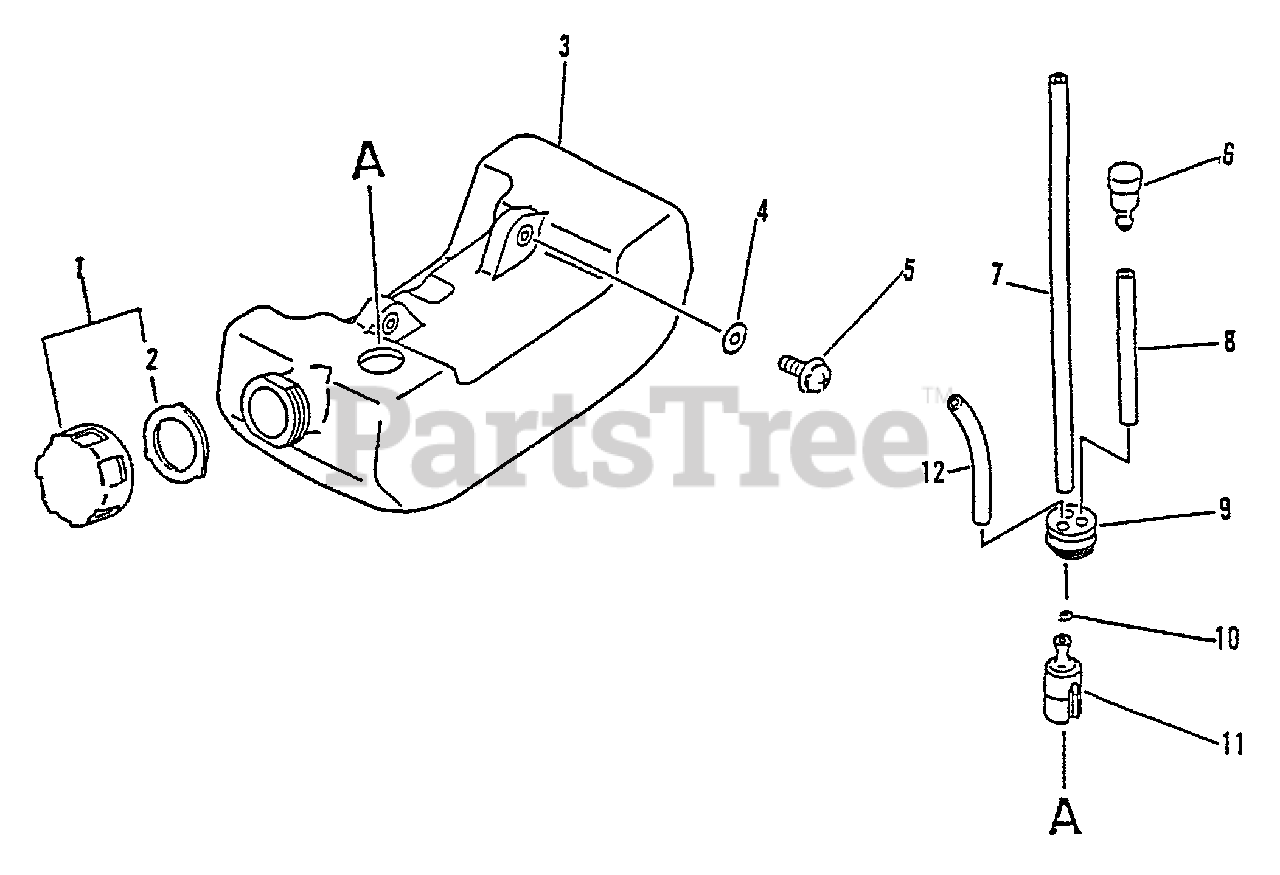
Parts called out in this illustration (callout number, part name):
1	CAP ASSY
2	GASKET, CAP
3	TANK, FUEL
4	WASHER - 5
5	SCREW - 5X16
6	VENT, FUEL TANK
7	PIPE - 3X5X180 -- BLACK
8	PIPE - 3X5X70 -- BLACK
9	GROMMET
10	CLIP - 6
11	FILTER, FUEL
12	PIPE - 3X6X80 -- CLEAR
